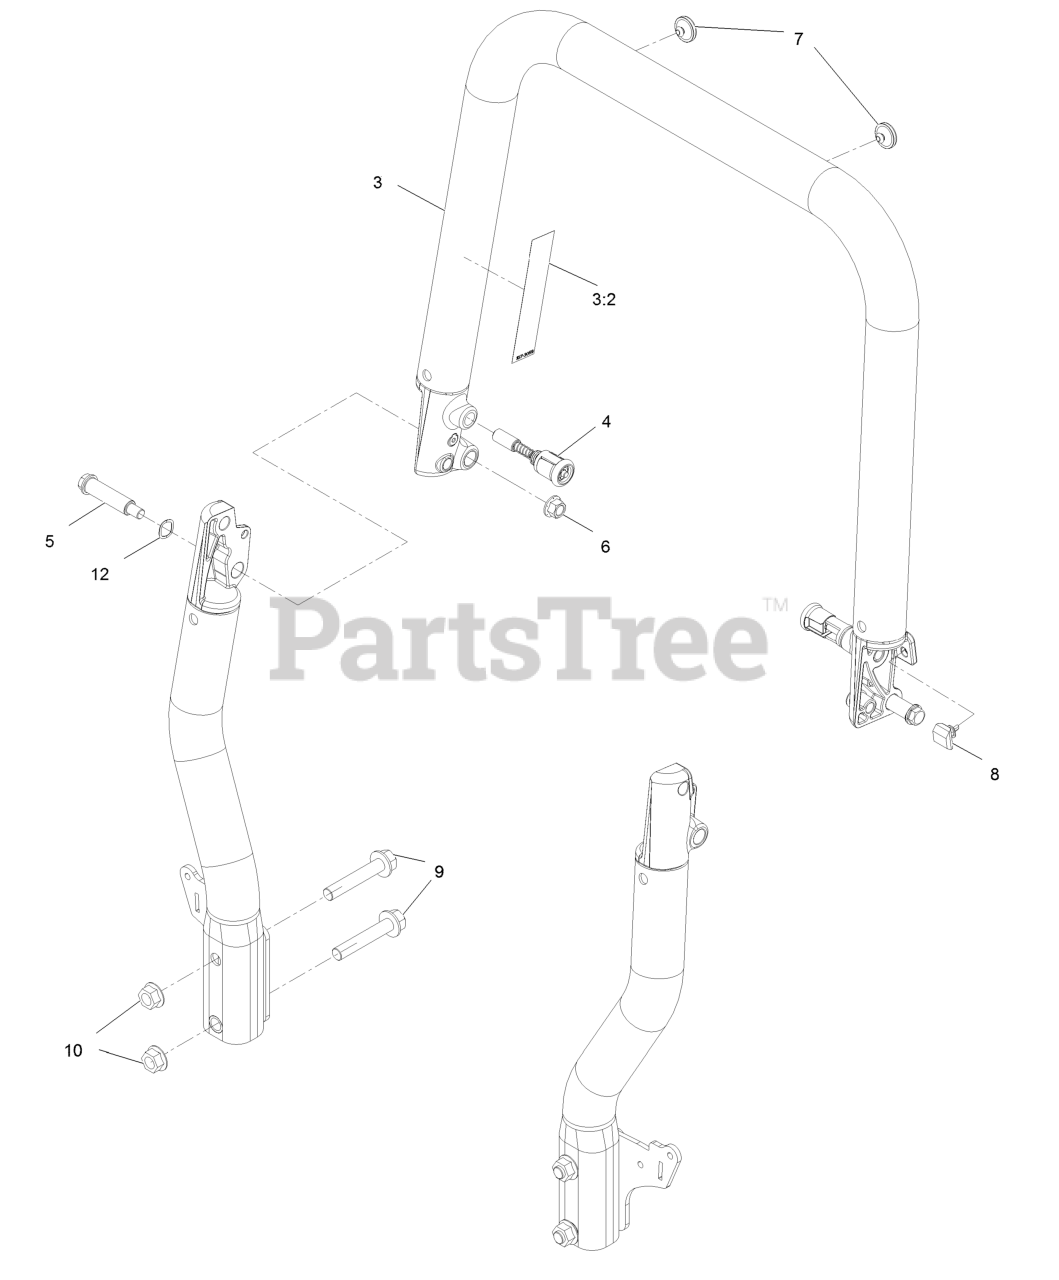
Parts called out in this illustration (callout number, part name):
3	Top Tube ASM
3:2	Decal-Warning
4	Pin-Spring
5	Bolt-Shoulder
6	Nut-Lock
7	Bumper-ROPS
8	Bumper-ROPS
9	Screw-HHF
10	Nut-Flange
12	Washer-Wave
